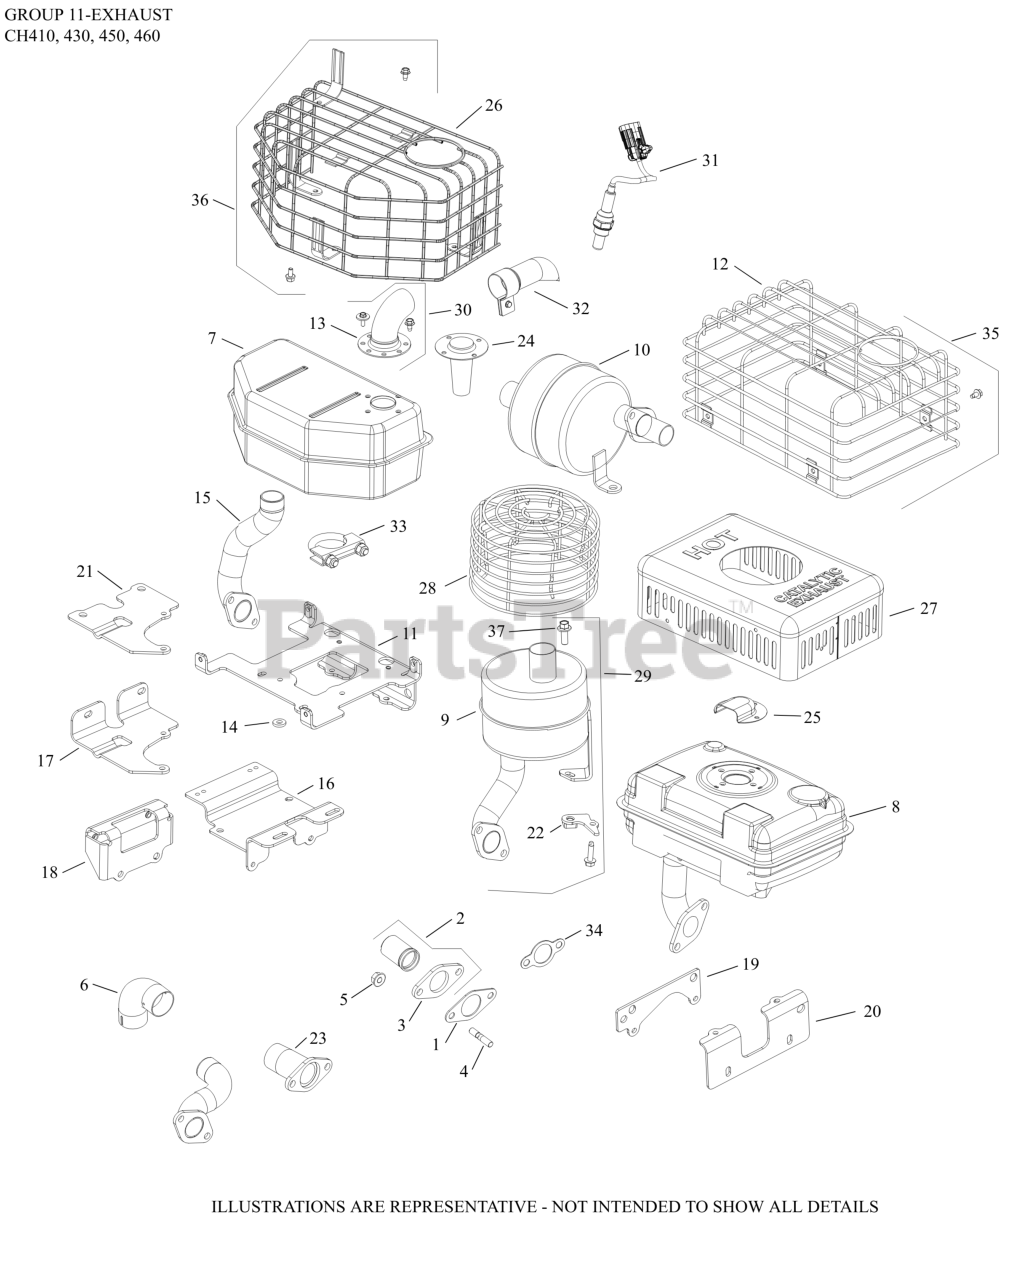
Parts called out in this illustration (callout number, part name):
1	GASKET, EXHAUST MANIFOLD
2	PIPE, INLET
3	FLANGE, MUFFLER
4	STUD, M8X1.25X38
5	NUT, FLG M8X1.25
